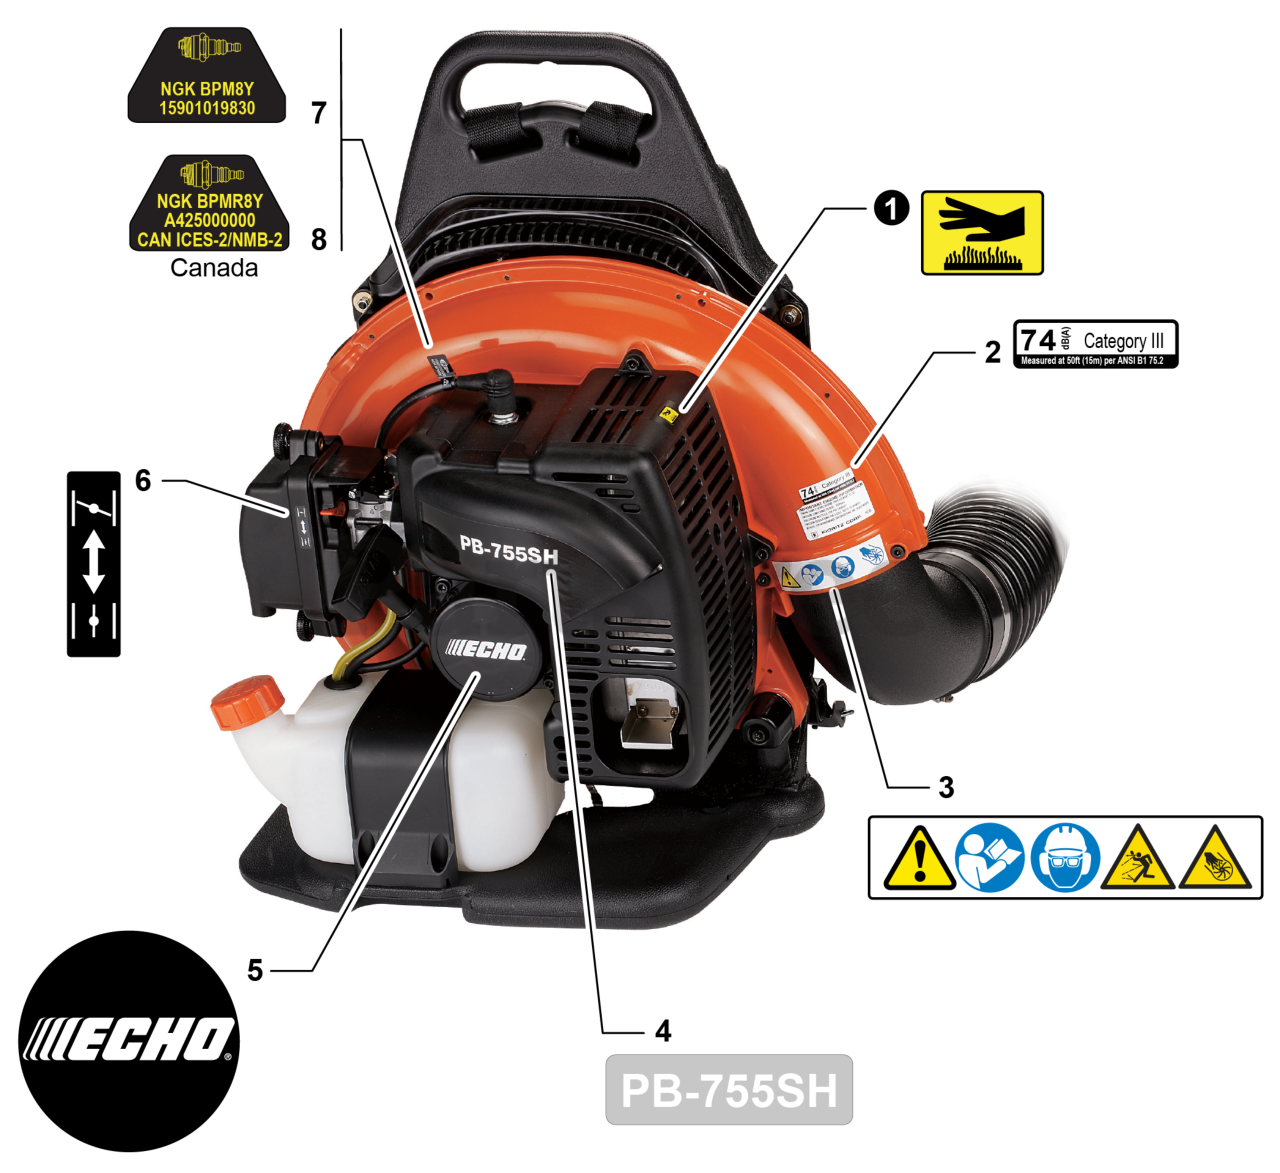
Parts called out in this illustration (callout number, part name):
1	LABEL - CAUTION - HOT
2	LABEL - NOISE - 74DB(A) CAT. III
3	LABEL - CAUTION - ISO
4	LABEL - MODEL PB-755SH
5	LABEL - STARTER - ECHO
6	LABEL - CHOKE
7	LABEL - SPARK PLUG - BPM8Y
8	LABEL - SPARK PLUG - BPMR8Y
